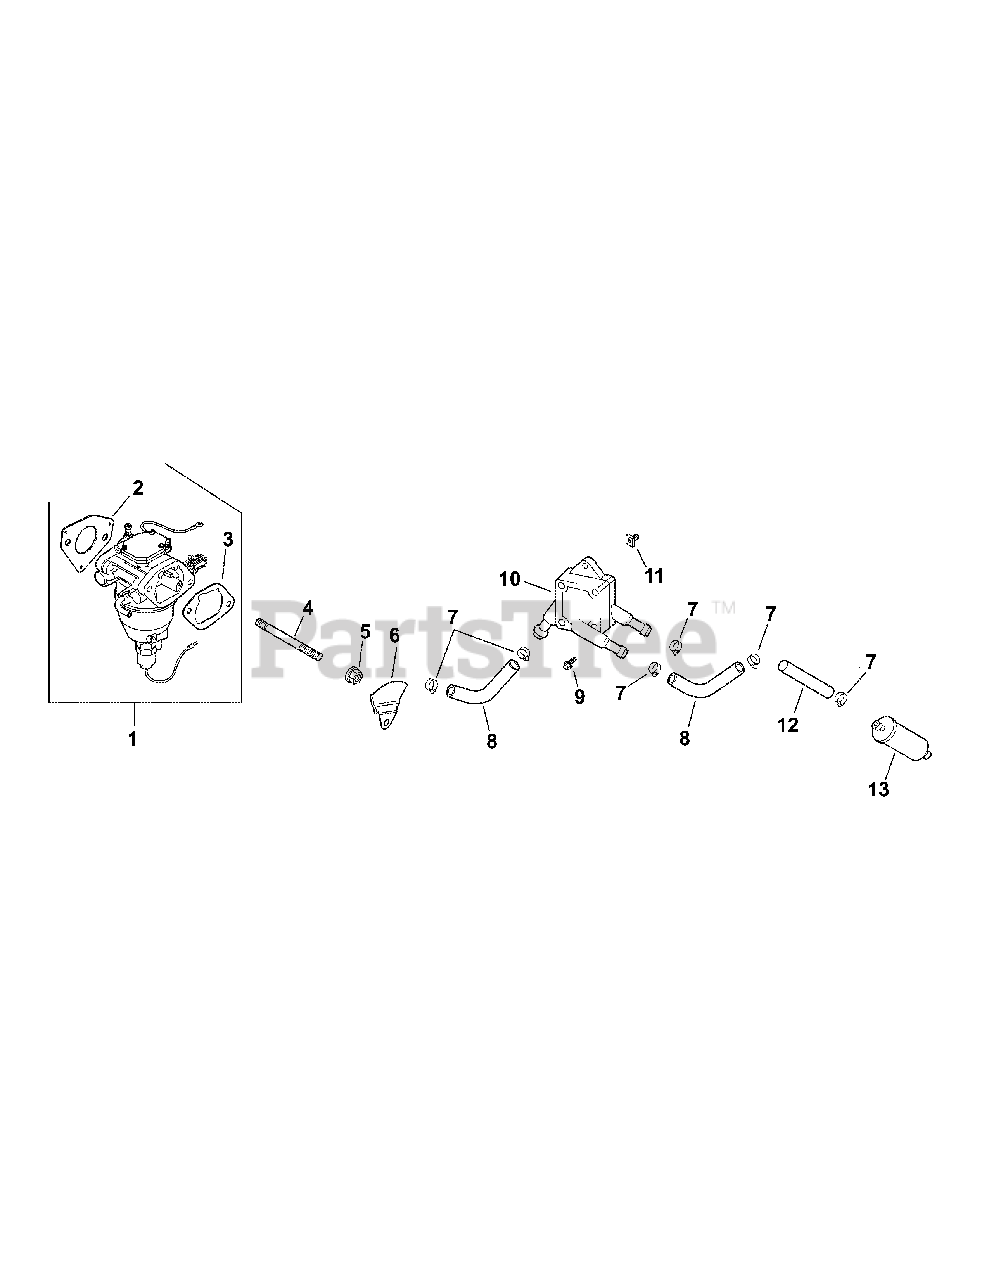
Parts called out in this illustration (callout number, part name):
1	KIT, CARBURETOR W/GASKETS
2	GASKET, CARBURETOR
3	GASKET, AIR CLEANER BASE
4	STUD, M6X1.0X96
5	NUT, FLG M6X1.0
6	BAFFLE, SPIT-BACK CUP
7	CLAMP, SPRING HOSE 1/2"
8	LINE, FUEL (24"-CUT TO LENGTH)
9	SCREW, TAP M6X1.7X18
11	NUT, PLASTIC-BLACK
12	LINE, FUEL 11"
13	FILTER, FUEL
